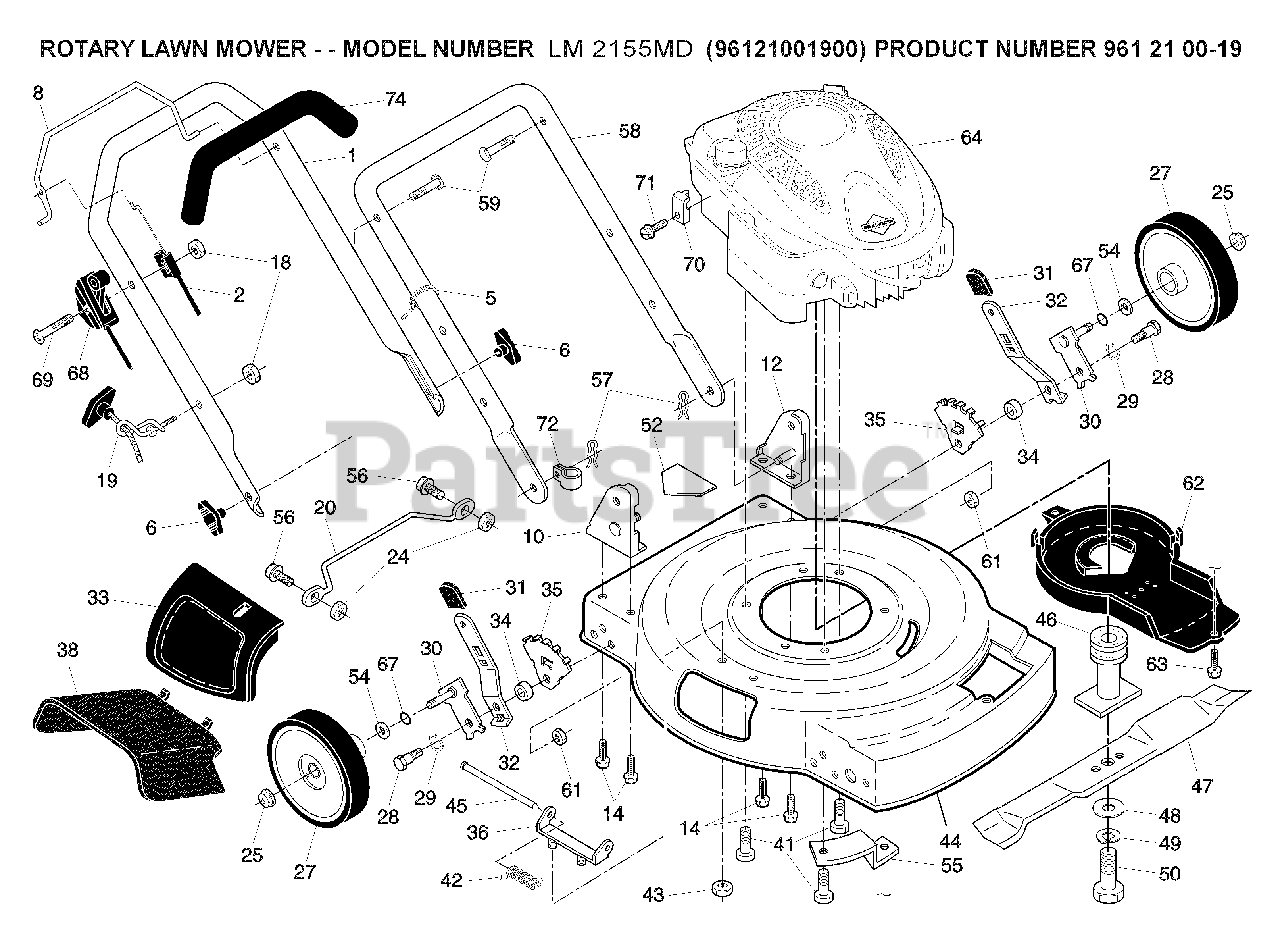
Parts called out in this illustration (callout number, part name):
2	ENGINE ZONE CONTROL CABLE
5	TIE GUIDE
6	KNOB, DEFLECTOR
10	HANDLE BRACKET ASM. RH
12	HANDLE BRACKET ASM. LH
14	SCREW 5/16-18
18	NUT
19	GUIDE.ROPE.STD.BLK.ZIN
25	NUT.HEX.FLANGE.3/8-16.LOCKNUT
28	BOLT SHOULDER 3/8 -16X1
29	WASHER FLAT
30	AXLE ARM ASSY.
31	SELECTOR KNOB
32	SPRING.SEL.EXT.21.DOMED.12/14
34	SPACER.HEIGHT.ADJUSTER
35	BRACKET.ADJ.WHEEL.5POS.ADS
36	HINGE BRACKET
41	BOLT 3/8-16X1-1/8
42	TORSION SPRING
43	LOCKNUT
45	ROD.HINGE.COMBI-C
46	ADAPTER.BLADE/PULLEY.25M
48	WASHER,HARDEN
49	LOCKWASHER
50	SCREW, HEX HD 3/8-24 X 1-3/8
52	DECAL.INTERNATIONL.CUTFINGER
54	WASHER PM
55	BRACKET
57	HAIRPIN COTTER
59	BOLT, HANDLE 5/16-18X1.75
61	LOCKNUT
62	DEBRIS SHIELD
63	SCREW.HEX.WSH
67	O-RING..070X.487.NEOPRENE
68	THROTTLE CONTROL
70	CABLE CLAMP(ENGINE)
71	SCREW.HEX.HEAD.WASHER.10-16
72	CLIP.CABLE.BLK
74	GRIP.HANDLE.FOAM
